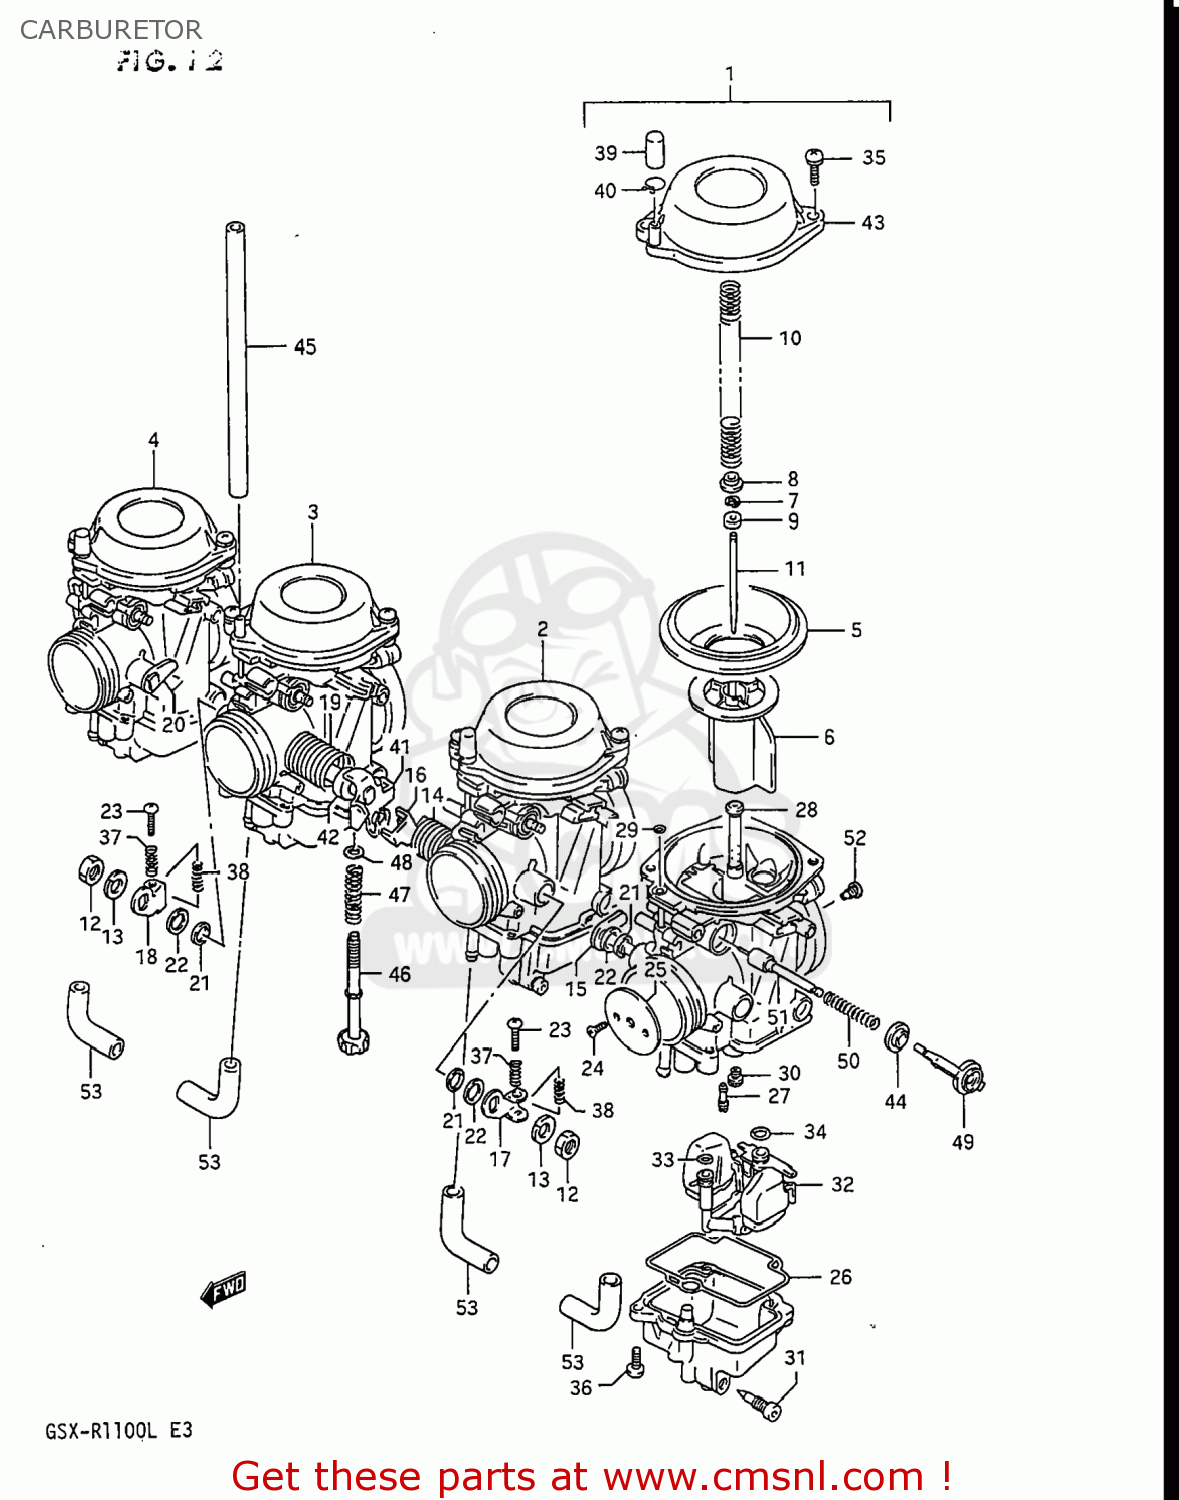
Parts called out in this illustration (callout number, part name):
1	CARBURETOR ASSEMBLY,LEFT
2	CARBURETOR ASSEMBLY,MIDDLE,LEFT
3	CARBURETOR ASSEMBLY,MIDDLE,RIGHT
4	CARBURETOR ASSEMBLY,RIGHT
5	DIAPHRAGM
6	VALVE,PISTON
7	CLIP
8	RING
9	RING
10	SPRING
11	NEEDLE,JET
12	NUT
13	WASHER,LOCK,8.
14	SPRING
15	SHAFT ASSEMBLY
16	SHAFT ASSEMBLY
17	LEVER
18	LEVER,THROTTLE
19	SPRING
20	SHAFT ASSEMBLY
21	SEAL
22	GASKET,THROTTLE SHAFT (NAS)
23	SCREW
24	SCREW
25	VALVE,THROTTLE(125)
26	GASKET,FLOAT CHAMBER (NAS)
27	JET,PILOT(30)
28	JET,NEEDLE(O-8)
29	O RING
30	JET,MAIN(122.5)
31	PLUG
32	FLOAT/NEEDLE VALVE ASSY
33	O RING
34	O-RING,NEEDLE VALVE
35	SCREW
36	SCREW
37	SPRING
38	SPRING
39	CAP
40	CLIP
41	SHAFT ASSEMBLY
42	RING
43	COVER,DIAPHRAGM
44	CAP,STARTER
45	HOSE
46	SCREW
47	SPRING
48	WASHER
49	HOLDER,GUIDE
50	SPRING
51	PLUNGER ASSY
52	JET,AIR(1.2)
53	HOSE
